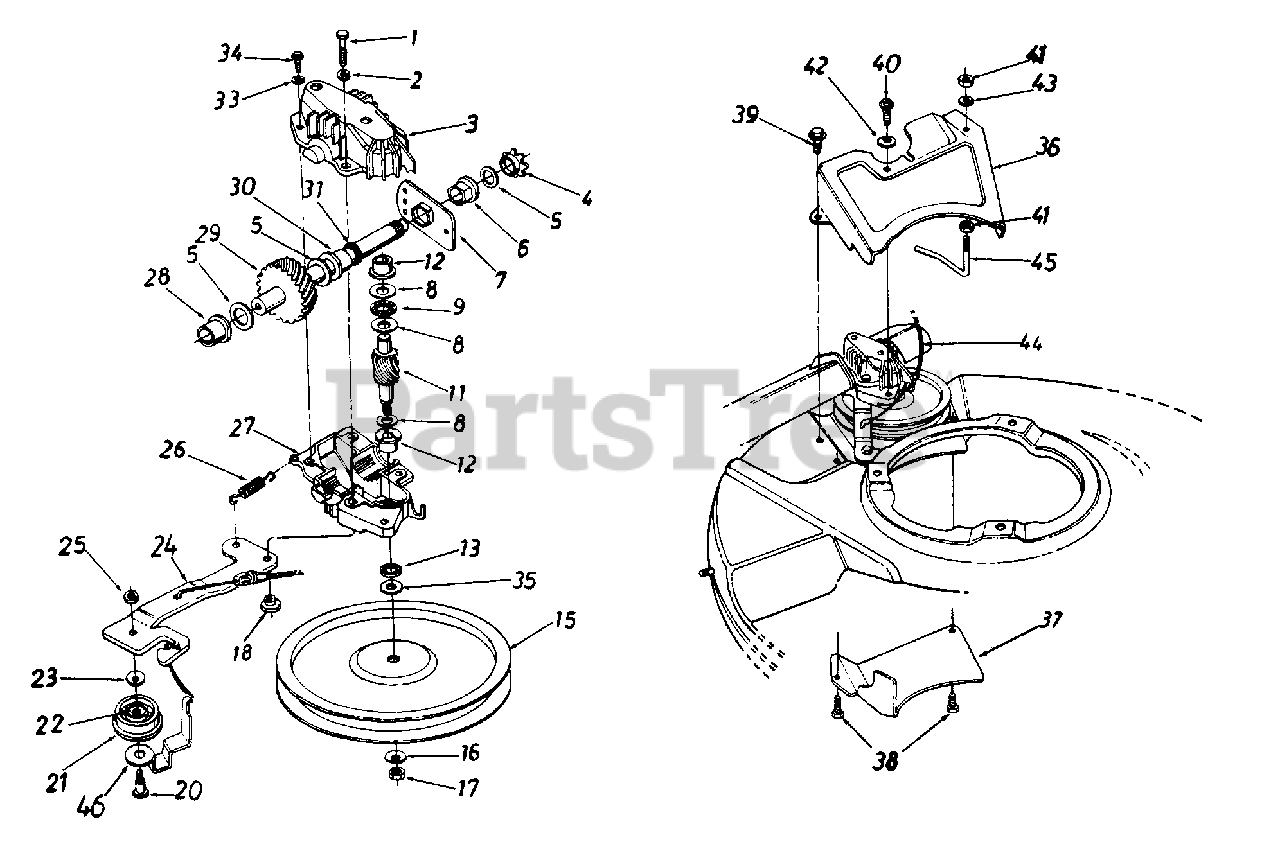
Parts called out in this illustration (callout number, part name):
1	Hex Bolt 1/4-20 x 1.25" Lg. w/Patch
2	L-Wash. 1/4" I.D.
3	Upper Hsg. Half
4	#48 Sprocket 7 Tooth x 1/2 Pitch
5	Fl-Wash. 5/8" I.D. x .030
6	Hex Flange Brg. .631" I.D.
8	Thrust Wash. .382" I.D. x 70" O.D.
9	Thrust Bearing .375" I.D. x .812" O.D.
11	11 Tooth Helical Gear
12	Flange Bearing
13	Oil Seal
15	Fl-Pulley 5.06" I.D.
16	Bell-Wash. .265" I.D. x .75"
17	Hex Nut 1/4-28 L.H. Thd.
18	Shld. Spacer .375" Dia. x .170
20	Shld. Bolt .375" Dia. x .40"
21	Fl-Idler Plastic 1.50" Dia.
22	Needle Brg. .375" x .31
23	Bell-Wash. .265" I.D. x .75"
24	Idler Brk't. Ass'y.
25	Hex Patch L-Nut 1/4-28 Thd.
26	Extension Spring 1.12" Lg.
27	Lower Hsg. Half
28	Flange Bearing .56 Dia.
29	Shaft Ass'y.
30	Flange Bearing .629 Dia.
31	Oil Seal .625 Dia.
33	L-Wash. #10 I.D.
34	Hex B-Tap Scr. #10 x .62"
35	Hex Washer .26" x .88"
39	Hex AB-Tap Scr. 1/4 x .50" Lg.
40	Hex B-Tap Scr. 1/4 x .62" Lg.
41	Hex Nut 1/4-20 Thd.
42	Bell-Wash. .265" I.D. x .75"
43	L-Wash. 1/4" I.D.
44	S.P. Cable - 48" Lg.
45	S.P. Belt Guard
46	Belt Keeper
